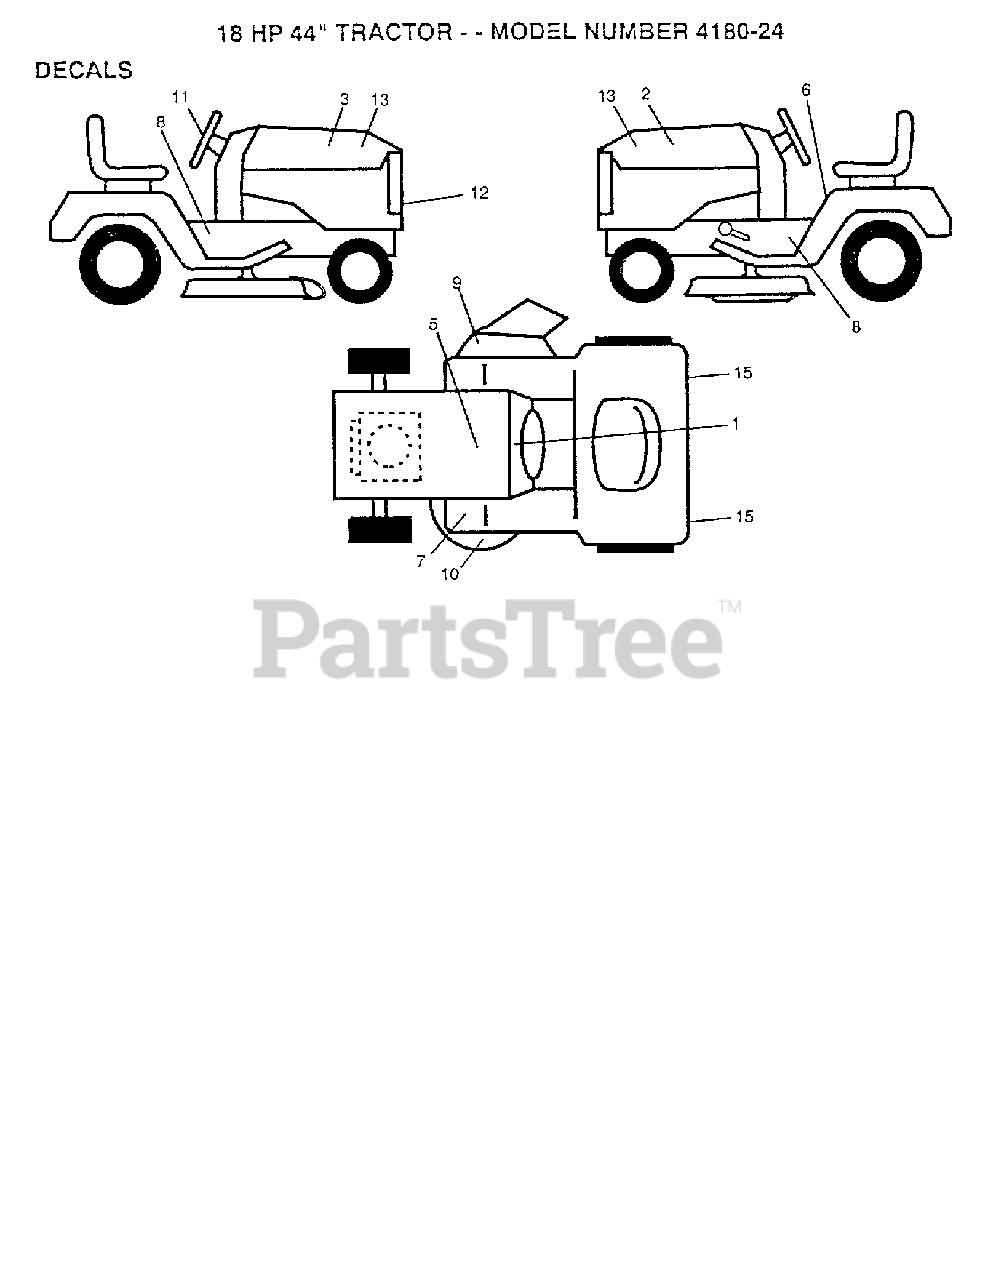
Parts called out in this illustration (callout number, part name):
1	DECAL YT
2	Poulan TBD
3	Poulan TBD
4	REFLECTOR-TAIL YT
6	DECAL CAUTION
8	Poulan TBD
9	DECAL WARNING
10	DECAL-INST YT
11	Poulan TBD
12	Poulan TBD
13	Poulan TBD
